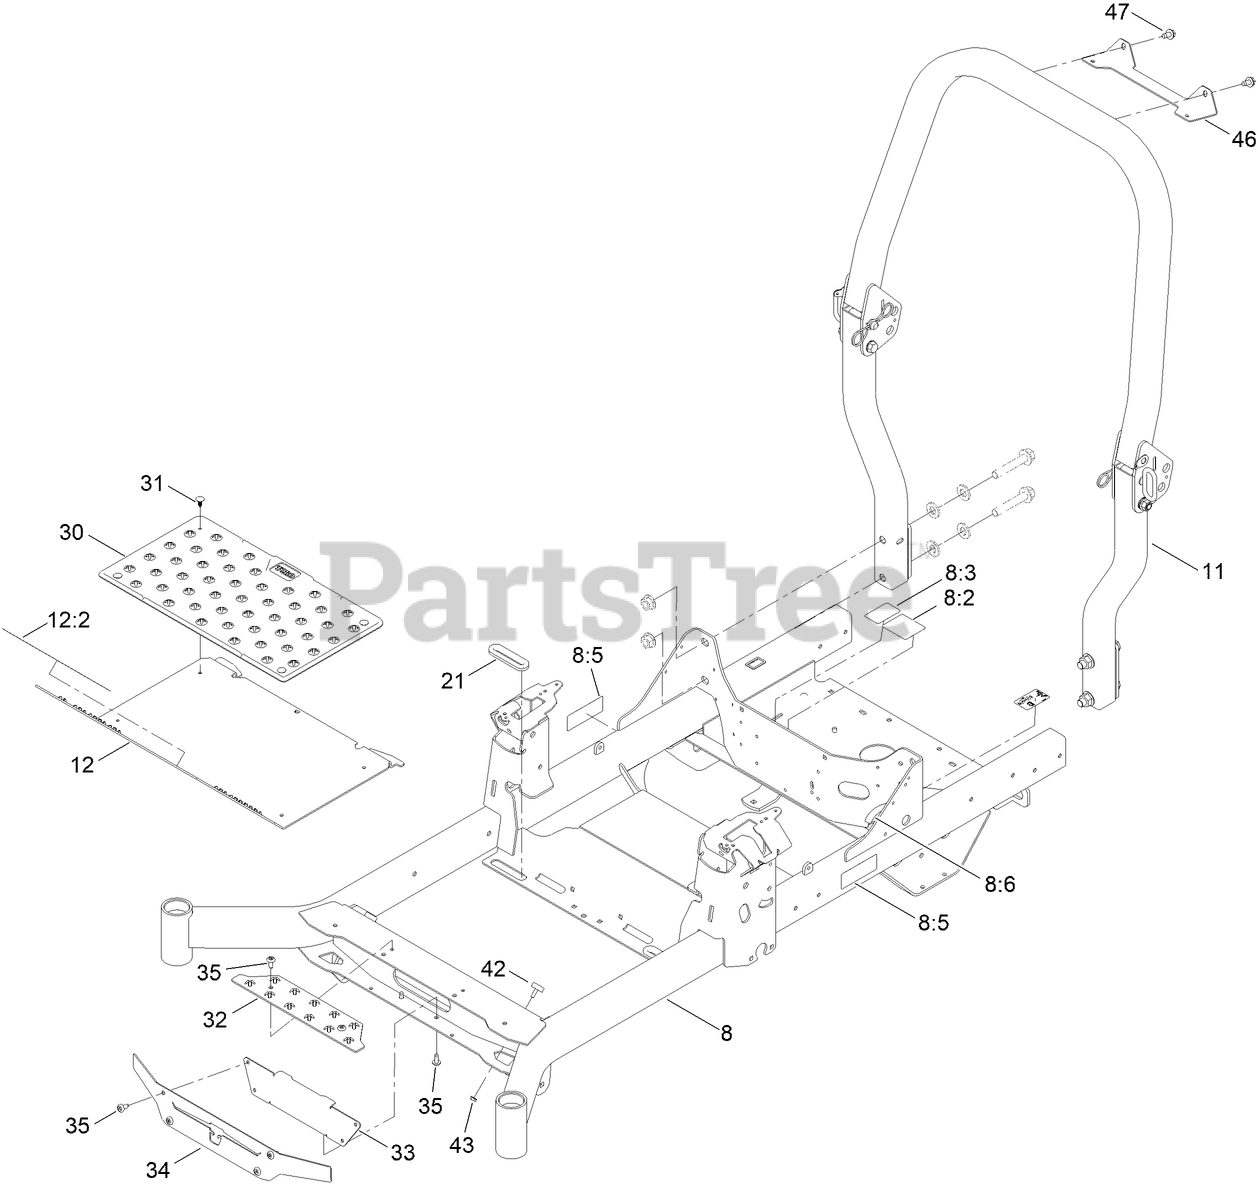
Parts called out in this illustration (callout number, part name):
8	FRAME-60 [W/DECALS]
8:2	DECAL-ROUTING, BELT
8:3	DECAL-RELEASE, DRIVE
8:5	DECAL-WARNING
8:6	STRIP-SEAL
11	ASM-ROPS
12	PAN-FLOOR ASM [SERVICE]
12:2	DECAL-DANGER
21	GROMMET-RUBBER
30	MAT-FLOOR
31	PLUG-PLASTIC
32	PLATE-STEP
33	PLATE-BACKER
34	PLATE-FASCIA
42	BUMPER-RUBBER
43	NUT-HF
46	BRACKET-LIGHT
47	SCREW-HWH
